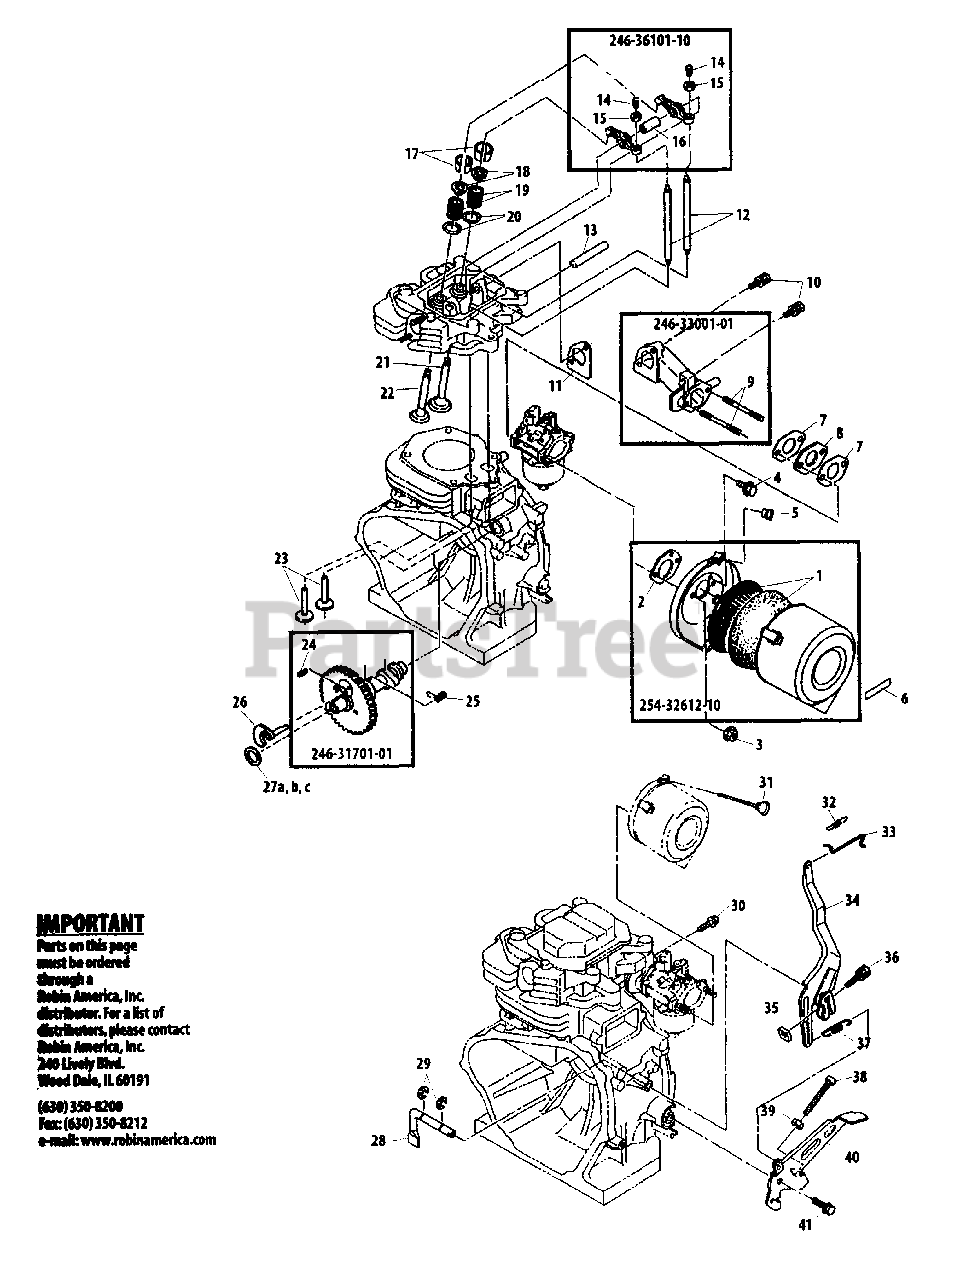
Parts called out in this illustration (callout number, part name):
1	ELEMENT
2	PACKING
3	NUT - FLANGE
4	BOLT
5	GROMMET
6	LABEL
7	GASKET, INTAKE
8	INSULATOR
9	STUD
10	BOLT
11	GASKET
12	PUSHROD
13	SHAFT, ROCKER
14	SCREW, ADJUST
15	NUT
16	SPACER
17	COLLET, VALVE
18	RETAINER, SPRING
19	SPRING, VALVE
20	WASHER
21	VALVE, INTAKE
22	VALVE, EXHAUST
23	TAPPET
24	PIN - SPRING
25	SPRING, RETURN
26	RELEASE LEVER
27A	SPACER - 0.6
27B	SPACER - 0.7
27C	SPACER - 0.8
28	GOVERNOR SHAFT
29	CLIP
30	BOLT - FLANGE
31	KNOB
32	ROD SPRING
33	ROD
34	LEVER, GOVERNOR
35	NUT
36	BOLT
37	GOVERNOR SPRING
38	SCREW
39	NUT
40	SPEED CONTROL
41	BOLT
246-31701-01	CAMSHAFT ASSY
246-33001-01	INTAKE PIPE ASSY
246-36101-10	ROCKER ARM ASSY
254-32612-10	AIR CLEANER ASSY
